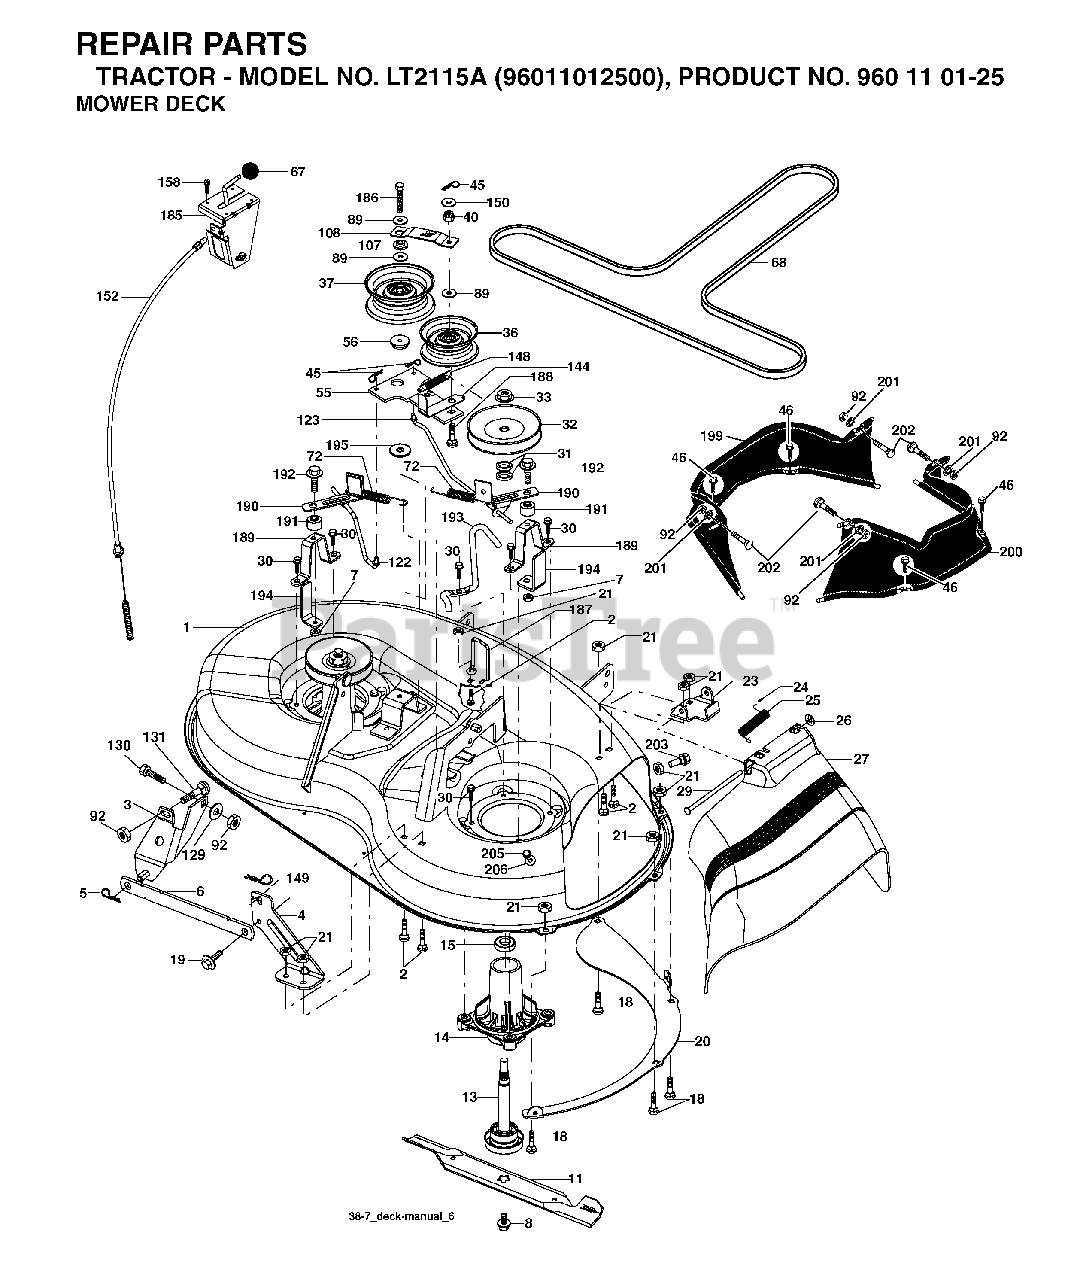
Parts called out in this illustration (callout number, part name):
1	DECK.WELDMENT.38"2005
2	BOLT
3	BRKT ASM SWAY BAR
4	BRACKET DECK SWAY BAR 38"/42"
5	RETAINER-SPRNG RB
6	BAR SWAY DECK
7	NUT.71038.31-18.HEX.NYLOCK
8	BOLT.WASHER.ASM.7/16-2
11	BLADE 38" PREMIUM
13	SHAFT.ASM.MDRL.N/GREASE.38
14	HOUSING MANDREL
18	BOLT
19	BOLT SHD 5/16-18
20	BAFFLE VORTEX
21	LOCKNUT
23	BRKT.DEFLECTOR.38"2005+
24	CAP-SLEEVE LT
25	SPRING.TORSION.DEFLECT
26	NUT PUSH M
29	ROD.HINGE
30	SCREW, WASHER HEAD
31	WASHER.SPACER.MANDREL
32	PULLEY MANDREL
33	NUT.FLANGE.LOCK.TOP
36	FLAT IDLER PULLEY
37	PULLEY.IDLER.FLAT.UNPLATED
40	LOCKNUT
45	RETAINER M
46	SCREW.1/4-20X5/8
55	IDLER ARM
56	SPACER.RETAINER.MOWER
67	KNOB T (3/8 HOLE)
68	V-BELT.MOWER.38"2005+
72	SPRING.BRAKE.RETURN.38"
89	WASHER
92	NUT
107	SPACER.IDLER.ARM
108	STIFFENER.IDLER.ARM
129	WASHER
131	BOLT D
144	KEEPER BELT
148	IDLER RETURN SPRING
149	SPRING.RETAINER.YELLOW.ZINC
150	WASHER LT
152	CABLE.CLUTCH.38".SERVICE
158	SCREW
185	HEAD ASM. CABLE CLUTCH
186	SCREW.HXWSH.3/8
187	KEEPER BELT
188	BOLT, CARRIAGE IDLER
189	STAND, BRAKE
190	ARM, BRAKE
191	SPACER, BRAKE
192	BOLT/WASHER ASM 5/16-18
193	KEEPER BELT RH MANDREL
194	GUARD BRAKE
195	WASHER 12/32X2X10GA
201	PUSH.NUT.ROUND.3/8.DIAM
205	SCREW
